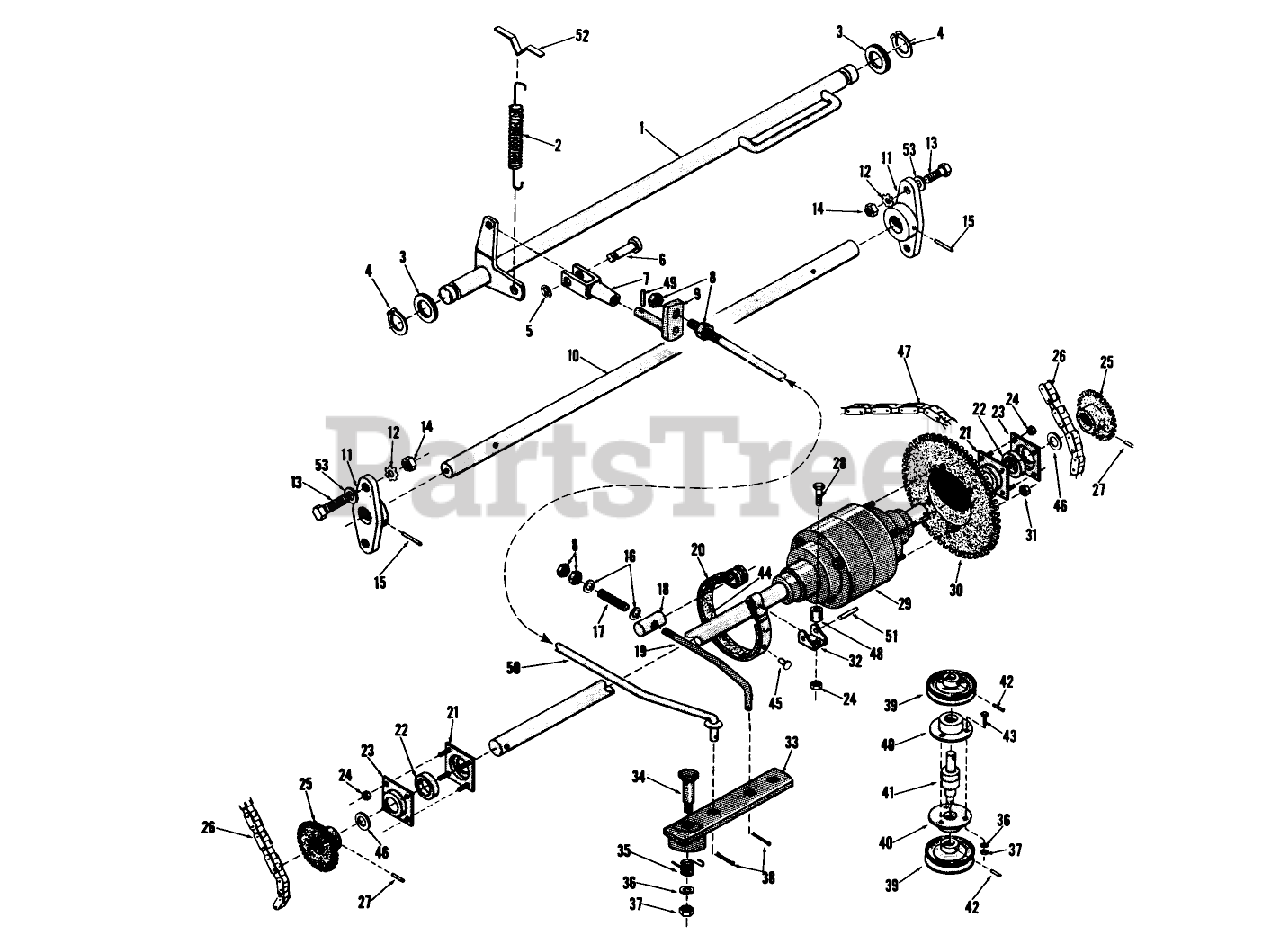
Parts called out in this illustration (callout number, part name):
1	Pivot Shaft
2	Spring
5	RING-RETAINING, EXT
6	Yoke Pin
8	NUT-JAM
9	Bracket
10	Axle Shaft
11	Shaft Retainer
12	WASHER-LOCK
13	SCREW-HH
14	NUT-HEX
15	PIN-ROLL
16	WASHER-PLAIN
17	Spring
19	Brake Rod
20	Brake Band Asm
21	Bearing Retainer
24	NUT-KEPS
25	Sprocket
27	PIN-ROLL
28	SCREW-HH
29	Differential Assy.
31	NUT-LOCK, INSERT
32	Bracket
33	Engaging Arm Assy.
35	Spring
36	WASHER-LOCK
37	NUT-HEX
38	PIN-COTTER
40	Bearing Housing
41	Bearing
42	PIN-ROLL
43	SCREW-HH
44	Lining
45	Rivet
46	Washer
48	Spacer
49	PIN-ROLL, SLOTTED
51	PIN-ROLL
52	Clip, Anchor
53	WASHER-FLAT
